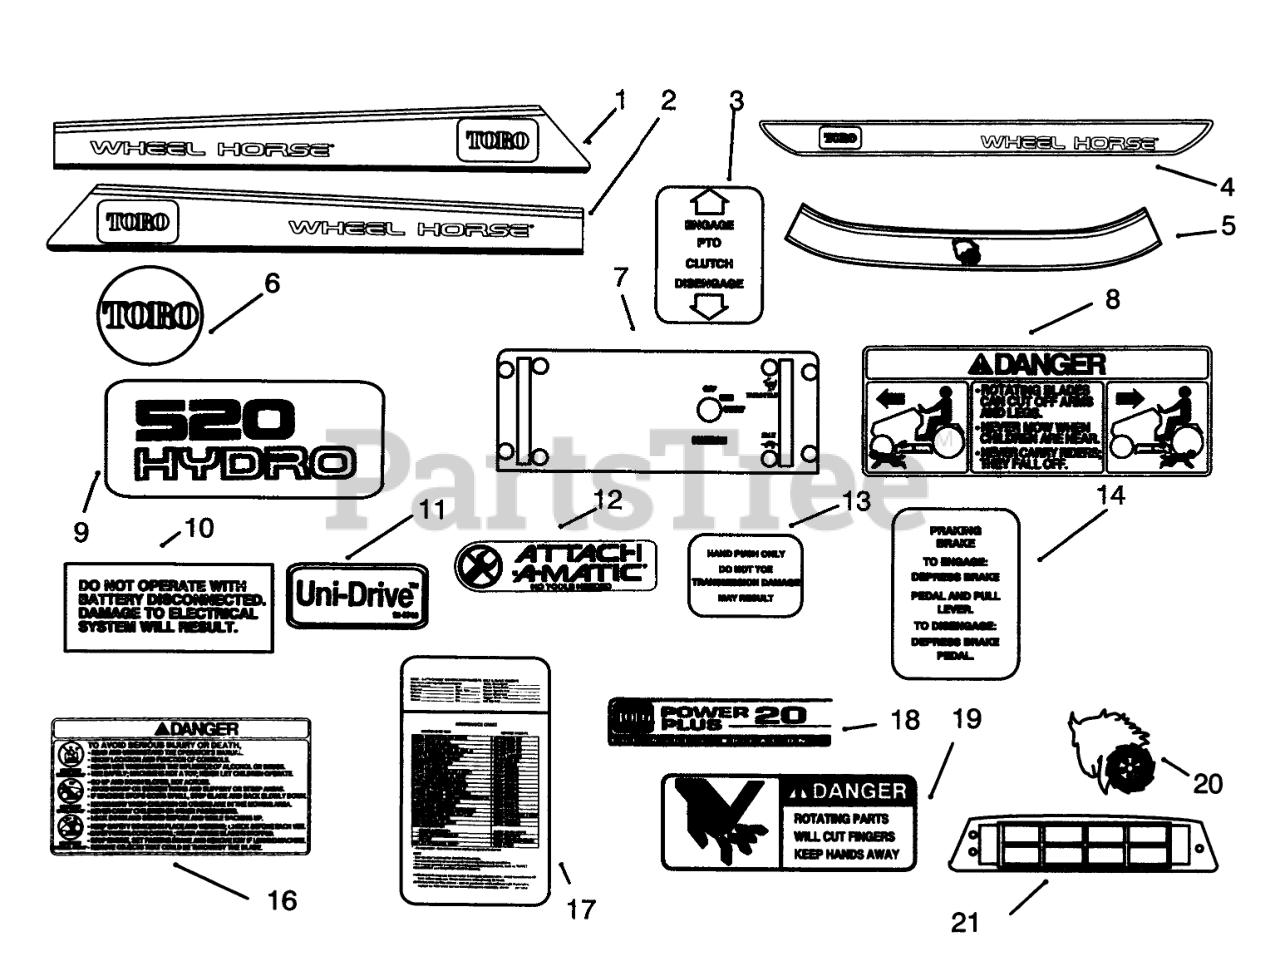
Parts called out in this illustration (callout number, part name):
1	DECAL - RH HOOD TOP
2	DECAL - LH HOOD TOP
3	DECAL PTO CLUTCH
4	DECAL - REAR FENDER
5	DECAL-FRONT HOOD, TOP
6	NAME-PLATE TORO LOGO
7	DECAL-FRONT PANEL
8	DECAL-DANGER
9	Decal-520 Hydro
10	DECAL ELECT SYSTEM
11	Decal-Unidrive
12	DECAL-ATTACH A-MATIC
13	DECAL-DO NOT TOW
14	DECAL-PARKING BRAKE
16	DECAL - DANGER
17	Decal-Maintenance
18	DECAL-PWR PLUS 20 PL
19	DECAL - DANGER
20	PLATE - LOGO WHL HORSE
21	DECAL-IND LIGHTS
